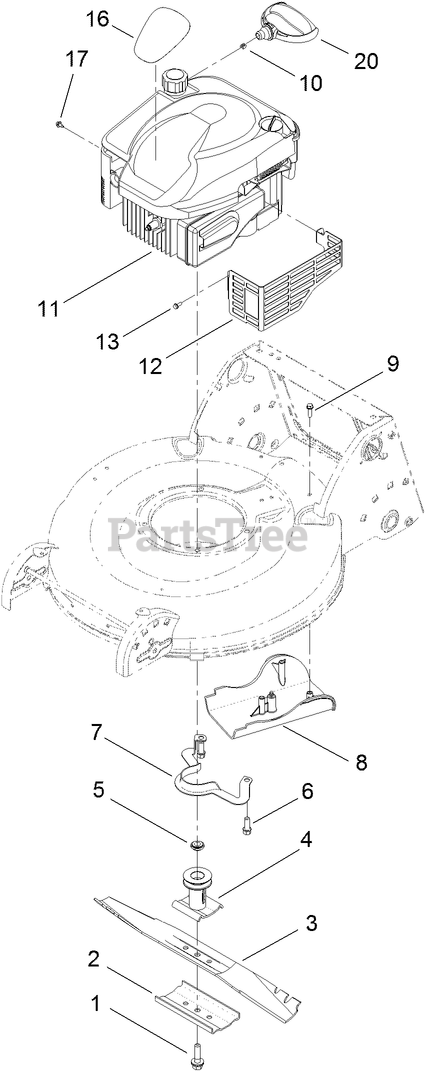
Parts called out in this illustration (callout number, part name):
2	SUPPORT-BLADE
4	DRIVER-BLADE
5	SPACER-DRIVER
8	COVER-BELT
9	SCREW-HWH
10	STOP-ROPE
12	SHIELD-MUFFLER
13	SCREW-TAPTITE
16	DECAL-ENGINE
17	SCREW-HWH
20	HANDLE-RECOIL
